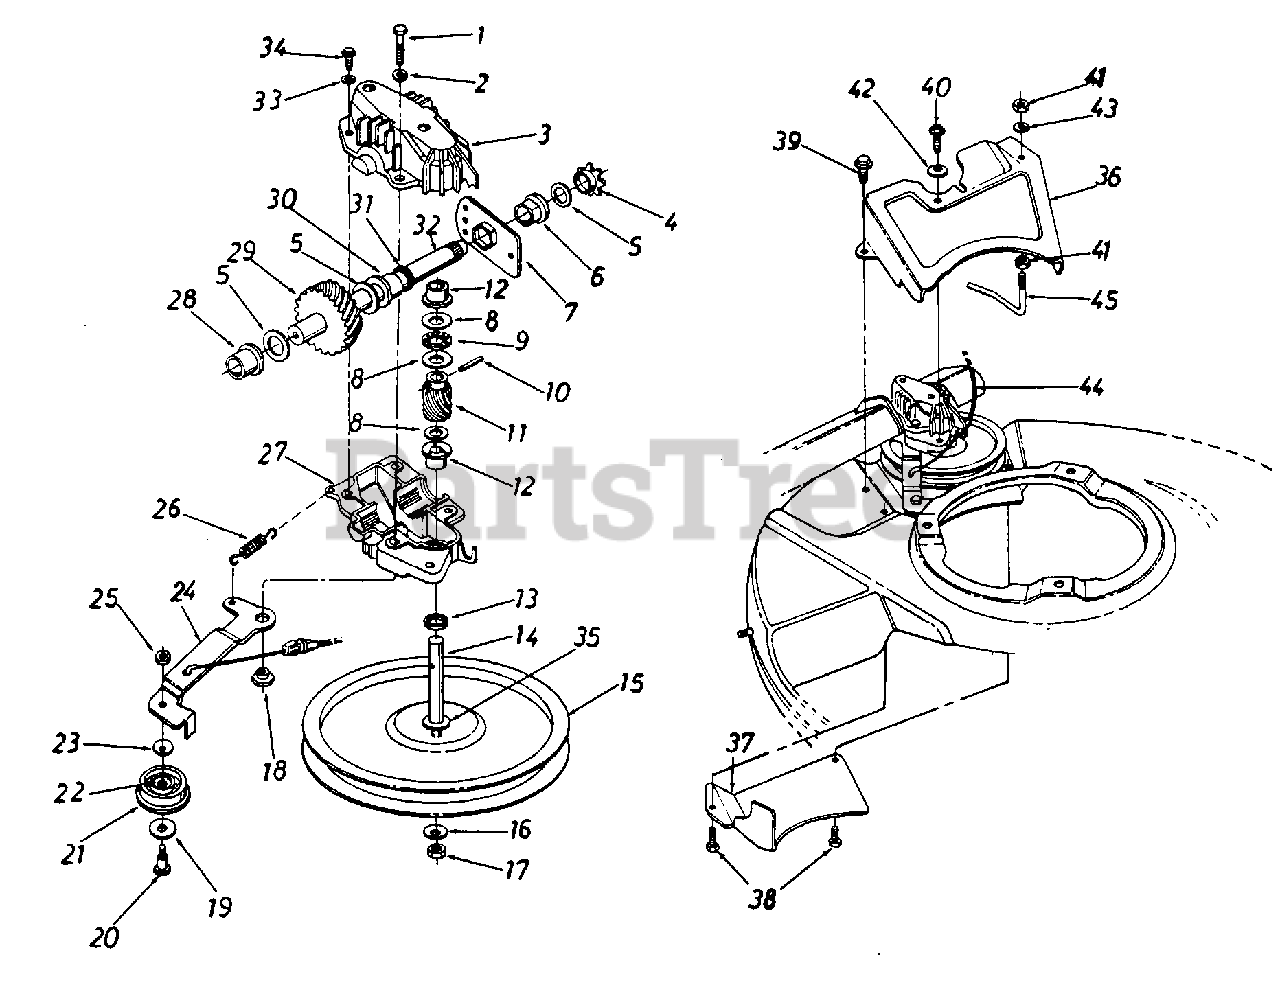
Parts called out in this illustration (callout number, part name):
1	SCREW-HEX 1/4-20 x 1.25
2	LOCK WASHER 1/4 DIA
3	HOUSING HALF-UPPER
4	SPROCKET-7T
5	WASHER-FL
6	BEARING-HEX FLANGE
7	BEARING-CUP HEX
8	WASHER-THRUST.382 x .684
9	BEARING-THRUST
10	PIN-SPRING-SPIR 1/8 x .625
11	GEAR-WORM
12	BEARING-FLANGE
13	SEAL-OIL-.375 ID
14	SHAFT-TRANS
16	WASHER-SPRING BELL
17	NUT-LH THD-1/4 x 28
18	SPACER-SHLD
19	WASHER-FL .995 x .032
20	SCREW-SHLD
21	KIT-PULLEY
22	BEARING-NEEDLE
23	WASHER-SPRING BELL
24	BRACKET ASSY-IDLER
25	NUT-HEX 1/4-28
26	SPRING-EXTENSION
27	HOUSING HALF-LOWER
28	BEARING-FLANGE
29	SHAFT-ASSY W/GEAR
30	BEARING-FLANGE
32	SHAFT-ASSY W/GEAR
33	WASHER-LOCK-#10
34	SCREW-HEX WASH HD TAP
35	WASHER-HEX
36	GUARD-BELT
37	COVER-BELT
38	SCREW-HEX B-TAP 1/4 x .38
39	SCREW-HEX WASH SF TAPP
40	SCREW-HEX B-TAP 1/4-.62
41	NUT-HEX 1/4-20
42	WASHER-SPRING BELL
43	LOCK WASHER 1/4 DIA
44	CABLE-CLUTCH x 50.0
45	GUARD-BELT
